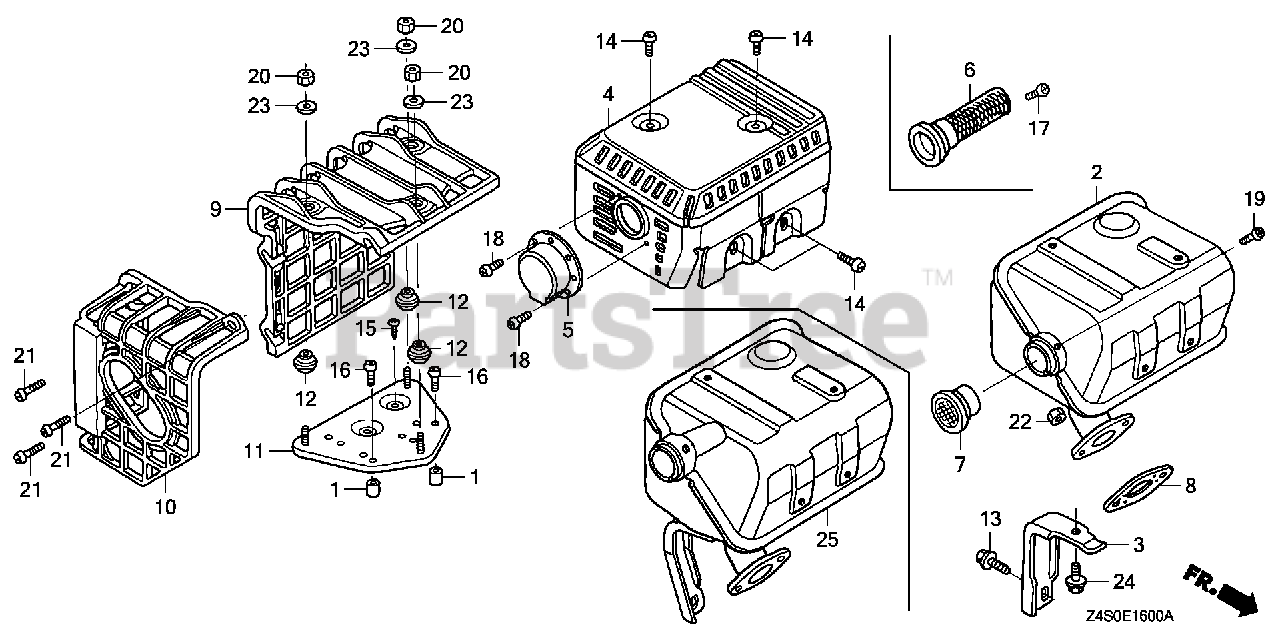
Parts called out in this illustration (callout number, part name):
3	STAY, MUFFLER
4	PROTECTOR, MUFFLER (SILENT)
6	ARRESTER, SPARK
7	NETTING, WIRE FLANGE
8	GASKET, MUFFLER
13	BOLT, FLANGE (6X13) (CT200)
14	SCREW, TAPPING (5X8)
17	SCREW, TAPPING (4X6)
19	SCREW, TAPPING (4X6)
22	NUT, HEX. (8MM)
24	BOLT, FLANGE (6X12)
